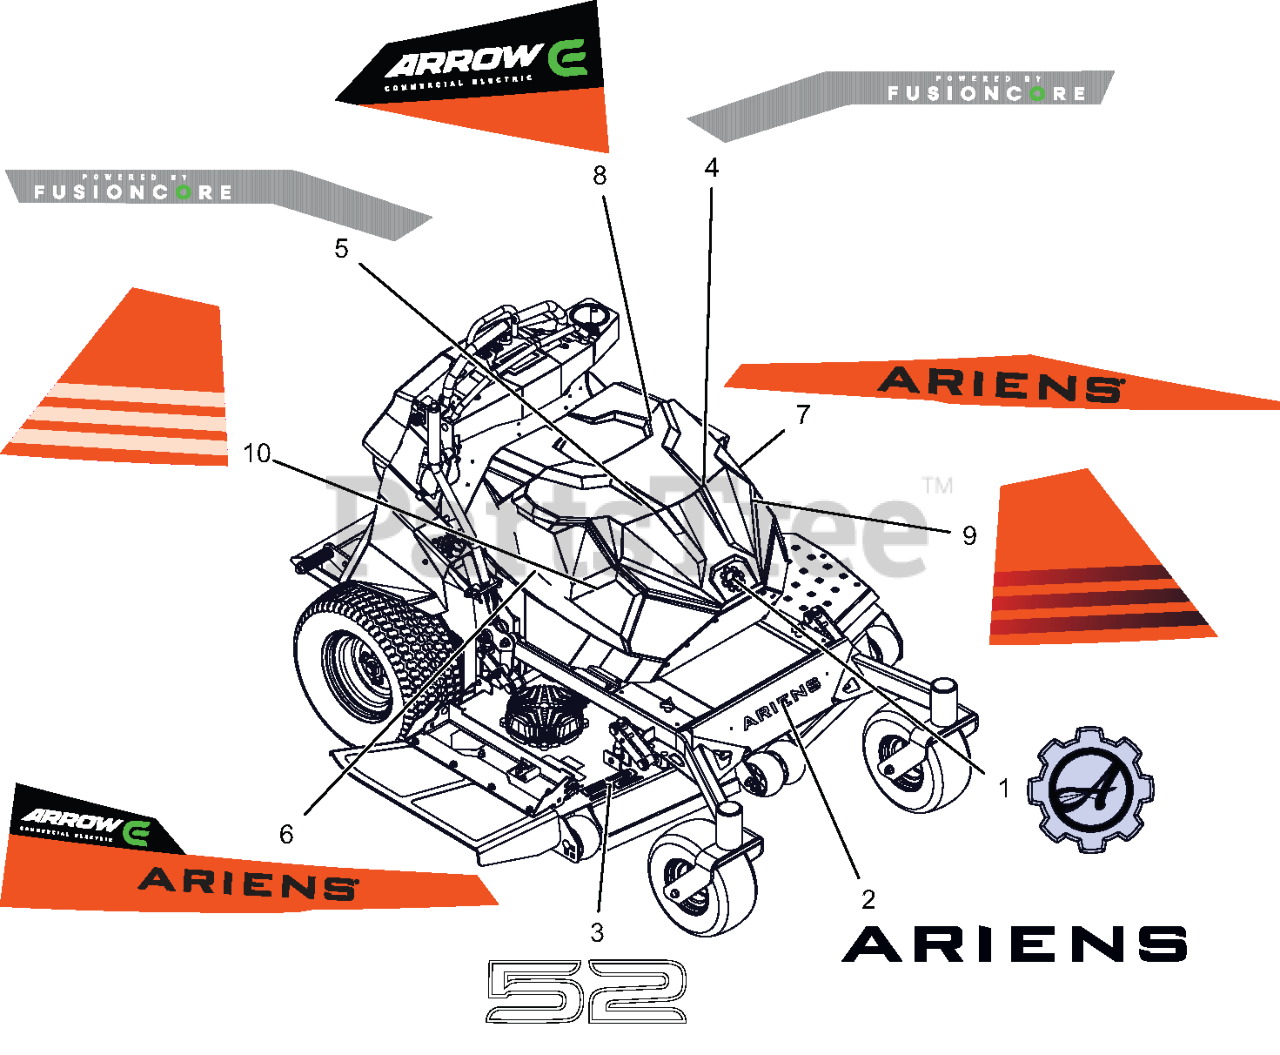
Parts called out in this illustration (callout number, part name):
1	DECAL- ARIENS GEAR BADGE
2	DECAL, ARIENS - 12.0"
3	DECAL, DECK - 52"
4	DECAL, ARROW E FUSION CORE RH
5	DECAL, ARROW E FUSION CORE LH
6	DECAL, ARROW E SIDE RH
7	DECAL, ARROW E SIDE LH
8	DECAL, ARROW REAR HOOD PSEV
9	DECAL, ARROW E FRONT HOOD
10	DECAL, ARROW E RH FENDER UPPER
